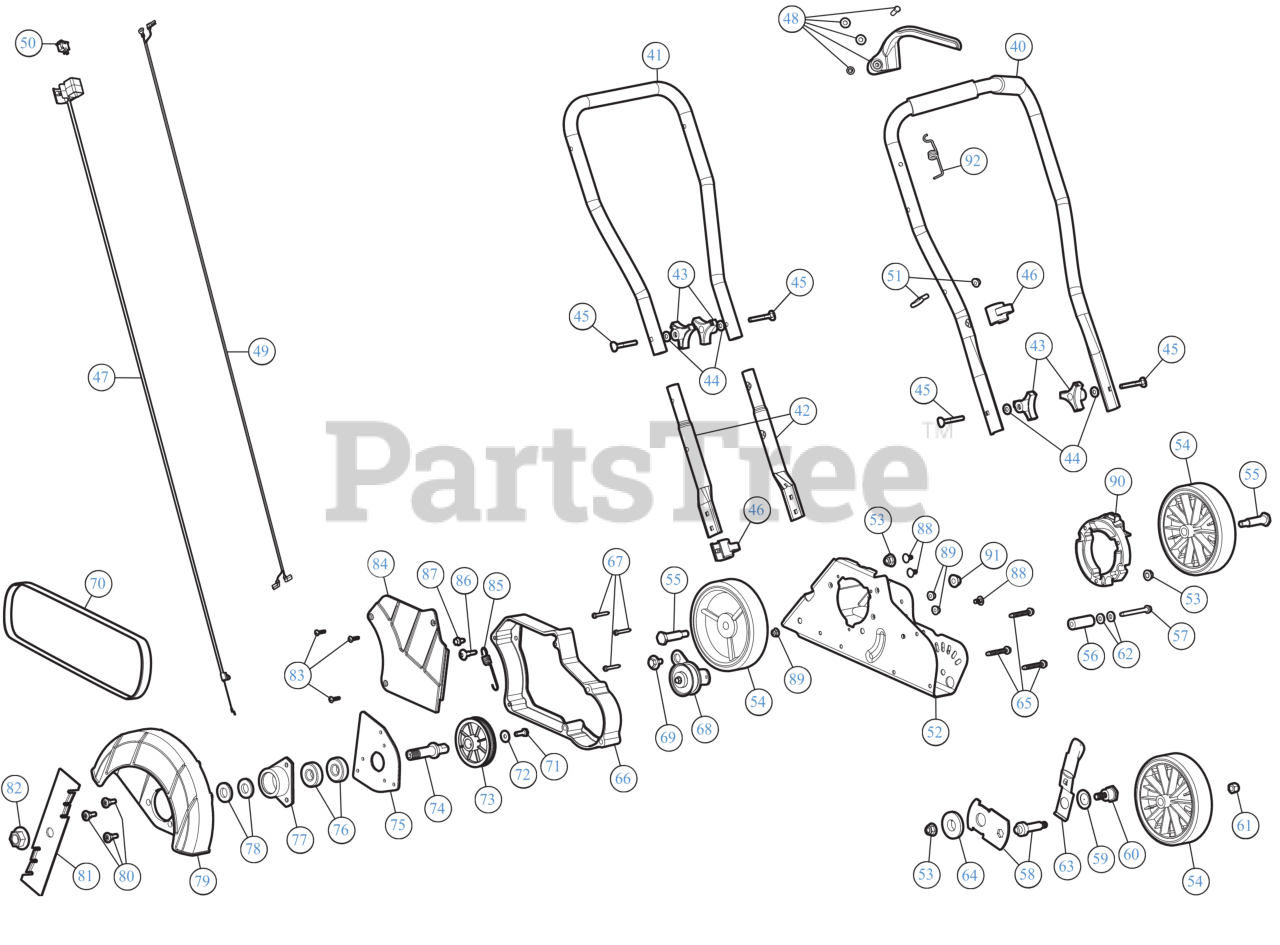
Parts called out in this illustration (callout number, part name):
40	HANDLE UP
41	HANDLE MID
42	HANDLE EXT
43	KNOB, 3-PRONG ¼ "-
44	WASH, FLAT SPECIAL
45	BOLT, CARRIAGE CRV
46	CABLE GUIDE
47	THROTTLE CABLE
48	THROTTLE LEVER
49	WIRE LEAD
50	SW, MOMENTARY ON/O
51	ROPE GUIDE
52	EDGER FRAME
54	WHEEL 5-1.5 GRAY
55	SHOULDER SCREW
56	SPACER
57	SCREW 1/4-20 x 2.375
58	PIVOT ARM
59	BELL WASHER
60	SHOULDER SCREW .75 X.50 X3/8-16
61	HEX NUT INS L-3/8-16
62	SPACER
63	FRONT HEIGHT ADJUST LEVER ASSEMBLY
64	HEIGHT ADJUSTMENT BEARING
65	SCREW 1/4-20 x 1.750
66	SPACER
67	SCREW 8-16X1.25
68	IDLER PULLEY ASSEMBLY
69	SHOULDER SCREW .560X.165: 5/16-18
71	SCREW 1/4-20X.75 GR5
72	SPRING WASHER BELL
74	BLADE SPINDLE
75	SPINDLE MOUNT PLATE
76	BALL BEARING
77	BEARING CUP
78	FLAT WASHER .635 x 1.24 x .181
79	EDGER BLADE GUARD (W/LABEL)
80	SHOULDER SCREW .375X.280:1/4-14
81	EDGER BLADE
82	HEX NUT
83	SCREW 8-16 x 3/4
84	BELT COVER
85	SPRING
86	BOLT 1/4-20
87	SCREW 1/4-20 X.500
88	CARRIAGE BOLT 1/4-20X.50"
89	FLANGE LOCK NUT
90	SPACER
92	SPRING
